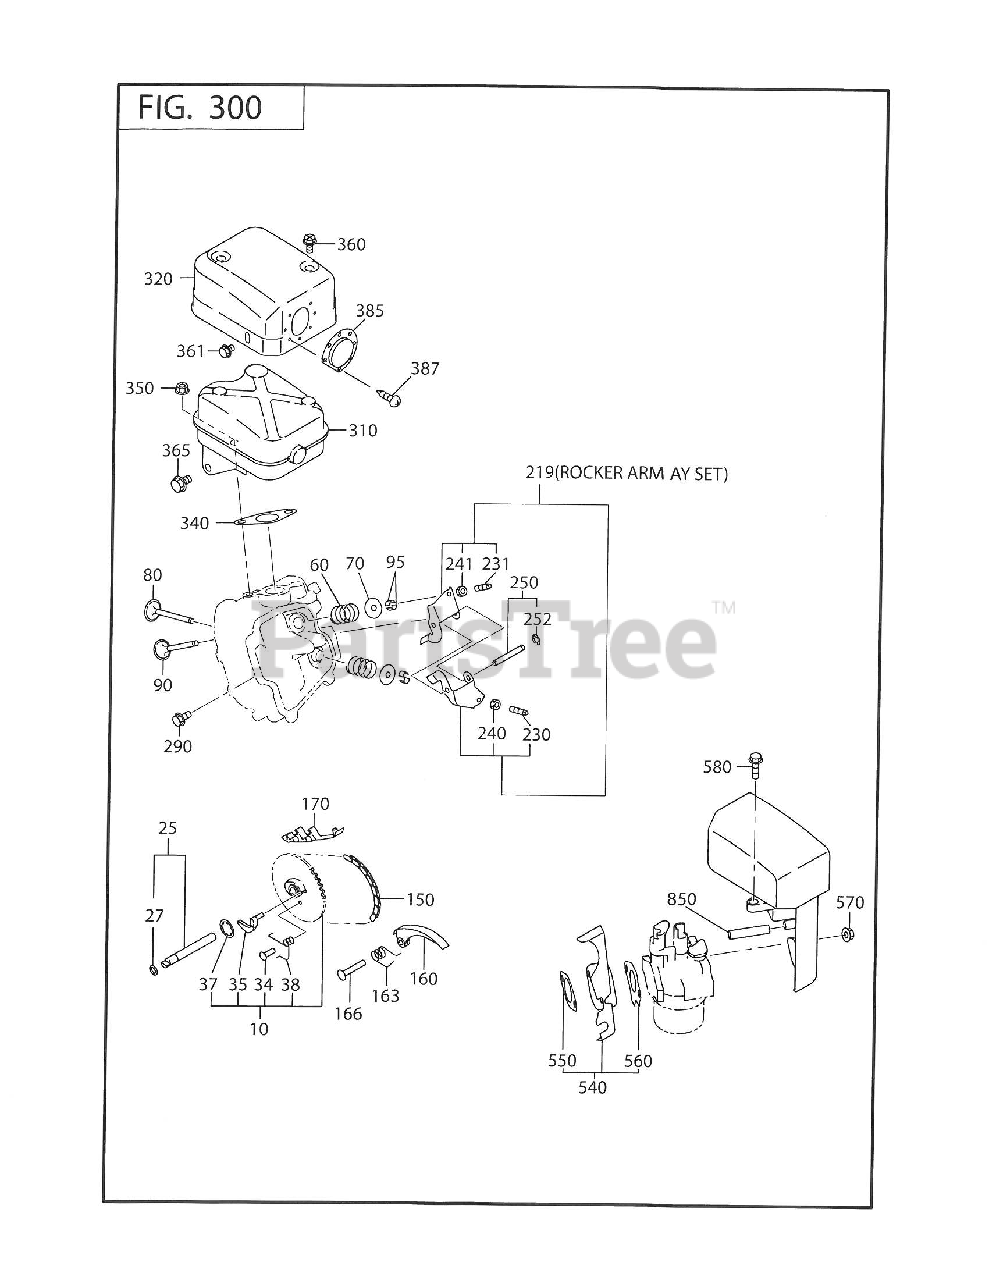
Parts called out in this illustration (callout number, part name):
10	GOVERNOR LEVER
20	GOVERNOR SHAFT
30	GOVERNOR ROD CP
60	BOLT AND WASHER AY
80	GOVERNOR SPRING
310	SPEED CONTROL LEVER
355	FRICTION WASHER
360	SCREW, PANHEAD
365	SPRING, ADJUST
396	SCREW AND WASHER AY
435	SPEED CONTROL BRACKET
